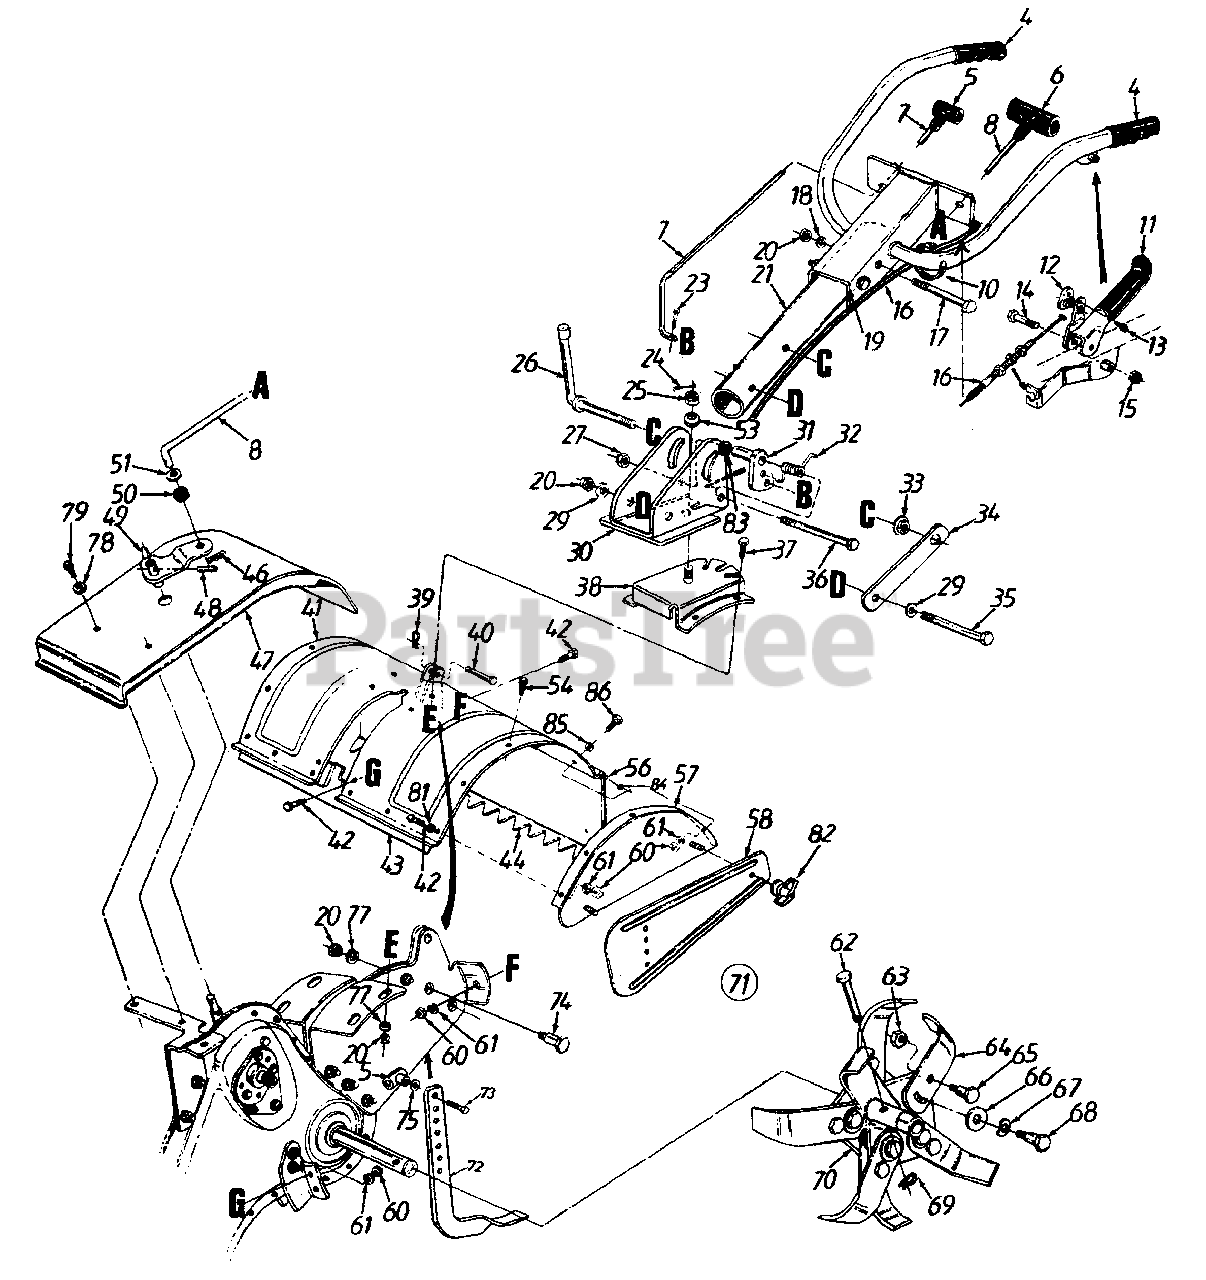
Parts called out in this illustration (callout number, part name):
4	Handle Grip
5	Small "T" Knob
6	Large "T" Knob
7	Clutch Rod
8	Control Rod 37" Lg.
10	Cable Tie-Self Clinching
12	Barrel Cable Hold Down
13	Hex B-Tap Scr. #10 x .44" Lg.
14	Hex Bolt 3/8-24 x 2.25" Lg.
15	Hex Jam L-Nut 3/8-24 Thd.
16	Clutch Control Cable 46" Lg.
17	Hex Bolt 3/8-16 x 3.00" Lg.
18	L-Wash. 3/8" I.D. - H.D.
24	Cotter Pin 3/32" Dia. x 1.25" Lg.
25	Hex Slotted Nut 5/8-18 Thd.
26	Handle Adj. Crank
27	Hex Cent. L-Nut 3/8-16 Thd.
29	Bell-Wash. .4" I.D. x .87" O.D.
32	Spring Handle Adj. (Torsion)
33	Hex Flange Nut 3/8-24 Thd.
34	Bracket Hex Nut Retainer
35	Hex Bolt 3/8-16 x 3.25" Lg.
36	Hex Bolt 3/8-16 x 3.00" Lg. - Gr. 8
37	Hex Bolt 3/8-16 x 1" Lg.
40	Clevis Pin .375" Dia.
43	Bracket Reinforcement - 18"
46	Intern. Cotter Pin 5/16" Dia.
49	Shifting Crank Ass'y.
50	Rubber Washer .33" I.D.
51	Fl-Wash. .4" I.D. x 1.25" O.D.
53	Bell-Wash. .63" I.D. x 1.25"
54	Hex Wash. Tap Scr.
56	Tiller Flap Rod
61	L-Wash. 5/16" I.D.
62	Clevis Pin .375" Dia.
63	Hex Nut 3/8-24 Thd.
65	Shld. Bolt 1/2" Dia. x .175
66	Fl-Wash. .51" I.D. x 1.50
67	Bell-Wash. .515" I.D. x 1.14"
68	Shld. Bolt 1/2" Dia. x .320
69	Intern. Cotter Pin
73	Hex Bolt 3/8-16 x 1" Lg.
74	Shld. Bolt 1/2" I.D. x .62" Lg.
75	Fl-Wash. 3/8" I.D. x 5/8" O.D.
77	L-Wash. 3/8" I.D.
78	Fl-Wash. .281" I.D. x .62"
79	Hex Wash. Self-Tap Scr. 1/4-20 x .50" Lg.
82	Plastic Knob 5/16-18 Thd.
83	Fl-Wash. .406" I.D. x .875" O.D.
85	Flat Washer
86	Shoulder Screw
